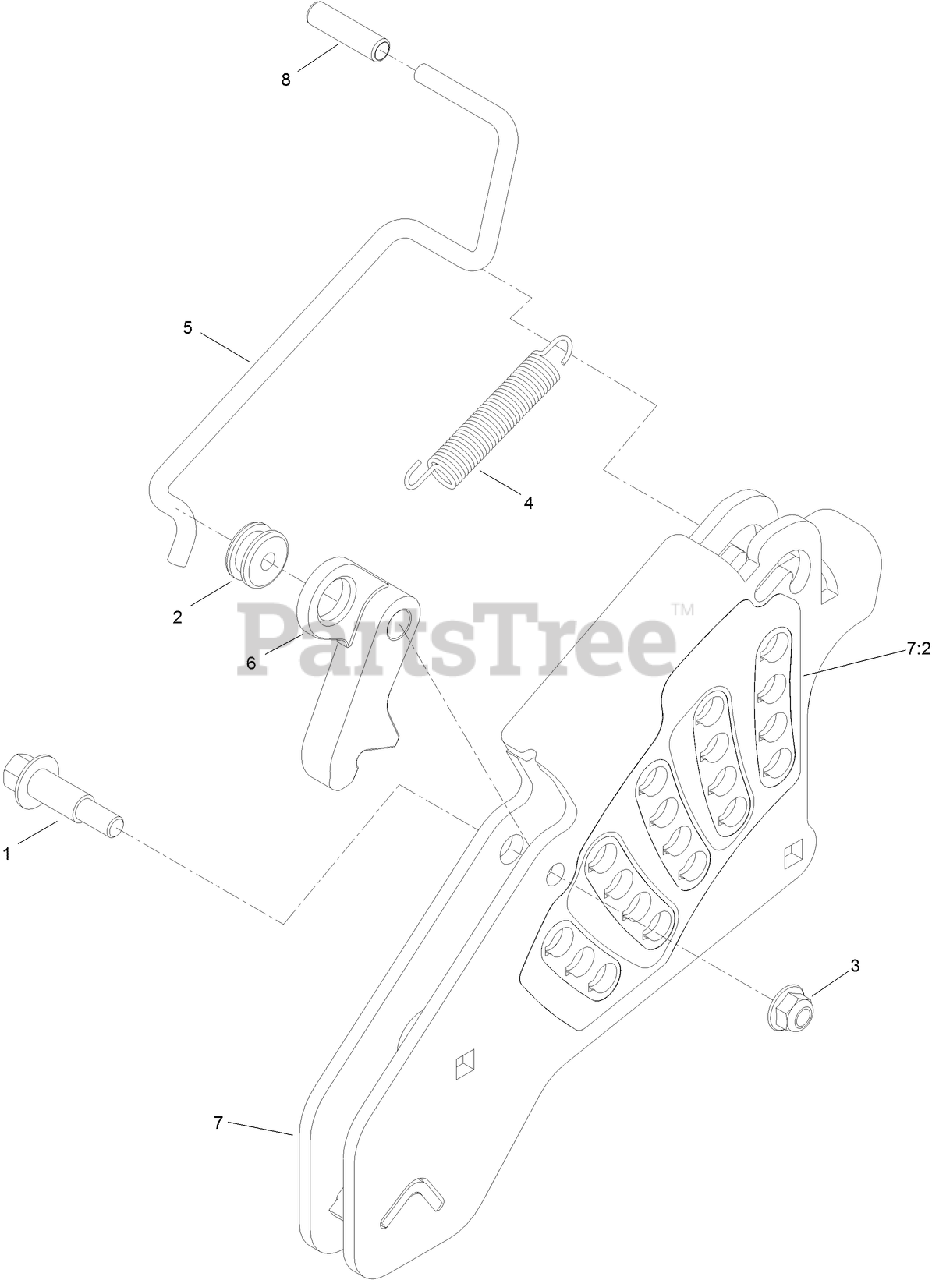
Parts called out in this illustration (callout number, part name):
1	BOLT-SHOULDER
2	GROMMET
3	NUT-HF, NI
4	SPRING-EXTENSION
5	ROD-LOCK, TRANSPORT
6	PAWL-TRANSPORT, HOC
7	HOC PLATE ASM
7:2	DECAL-HOC
8	GRIP-LEVER
